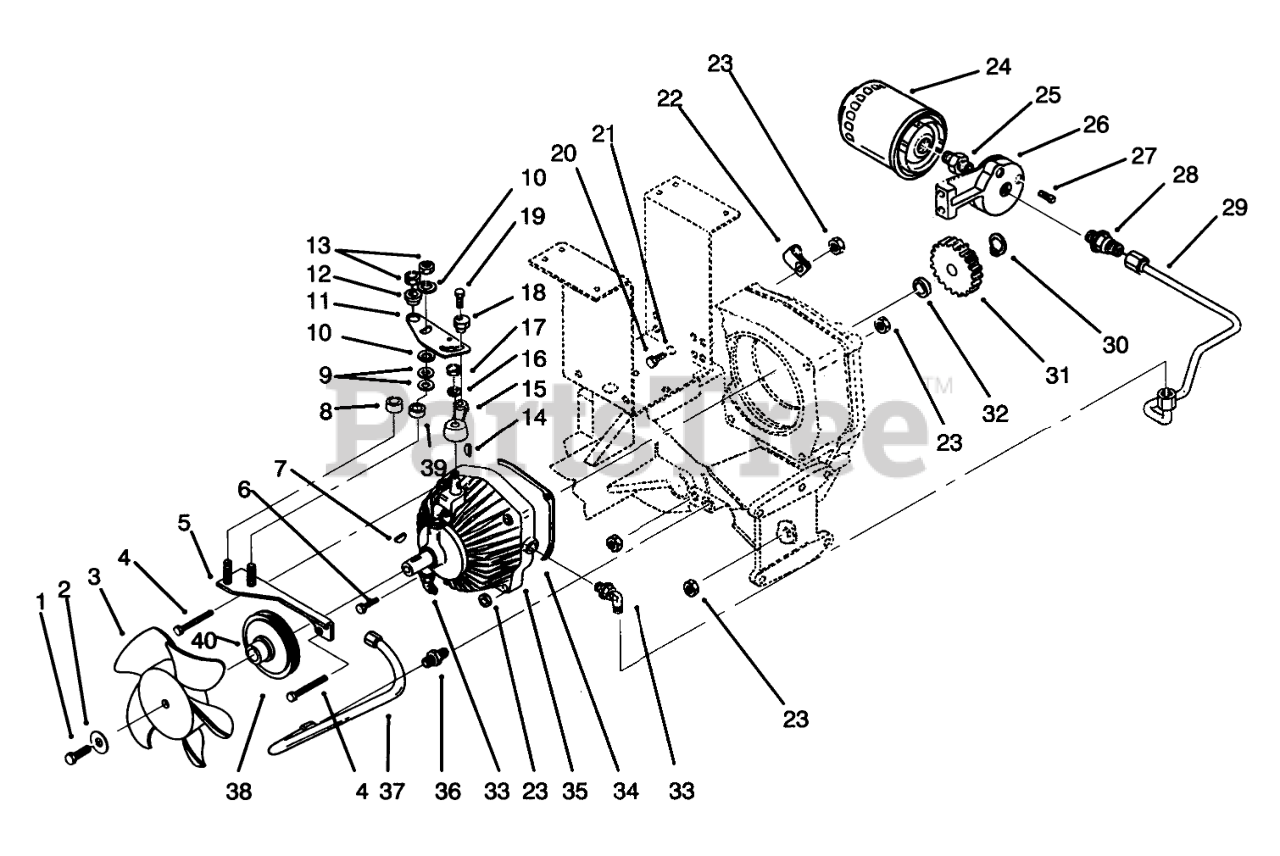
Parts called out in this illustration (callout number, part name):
1	SCREW-HEX HD CAP
2	WASHER
3	NYLON FAN-L-CW
4	SCREW-HH
5	ASSY-PLATE B
7	KEY-WOODRUFF
8	SPACER-PIVOT
9	WASHER-SPRING DISC
10	FRICTION WASHER
11	CAM-SPEED CONTROL (NS)
12	CAM-SPACER
14	KEY-WOODRUFF
15	ARM-SPEED CONTROLB
16	WASHER-FLAT
17	NUT-LOCK, NI
19	Screw-HH
20	SCREW-HH
21	WASHER-LOCK
22	CLIP
23	NUT-LOCK, NI
24	OIL FILTER ASM
25	FITTING
26	BASE-FILTER
28	Fitting-Hyd., Straight (Incl. "O" Ring)
29	ASS'Y-TUBE FILTER
30	RING-SNAP, EXTERNAL
31	GEAR 20 TEETH DRIVE
32	SPACER GEAR
33	ELBOW
34	GASKET
35	Pump & Motor
36	FITTING-TUBE
37	ASSY-TUBE SUCTION
38	PULLEY
39	SPACER-FRICTION
